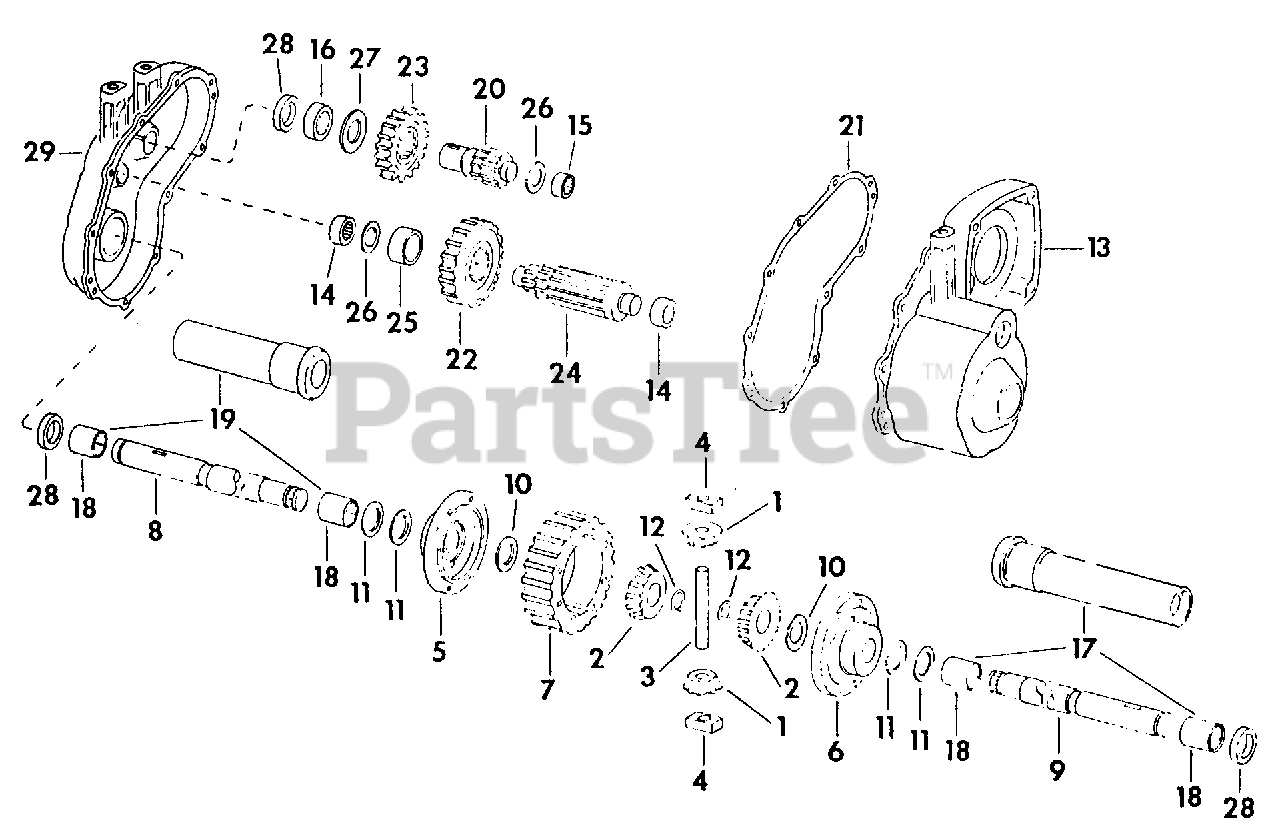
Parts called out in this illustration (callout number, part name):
1	Pinion, Bevel -14T
2	Gear, Bevel -24T
3	Pin, Drive
4	Block, Drive
5	Carrier, Differential
6	Carrier, Differential
11	Washer, Thrust
12	Ring, Retaining
14	Bearing, Needle
15	Bearing, Needle
16	Bearing, Needle
17	Housing w/Bushing, Axle RH
19	Housing w/Bushing, Axle LH
20	Shaft, Brake
21	Gasket, Case to Cover
22	Gear, Bevel Output -24T
23	Gear, Idler
24	Shaft, Output
27	Washer, Thrust
29	Cover Assy
